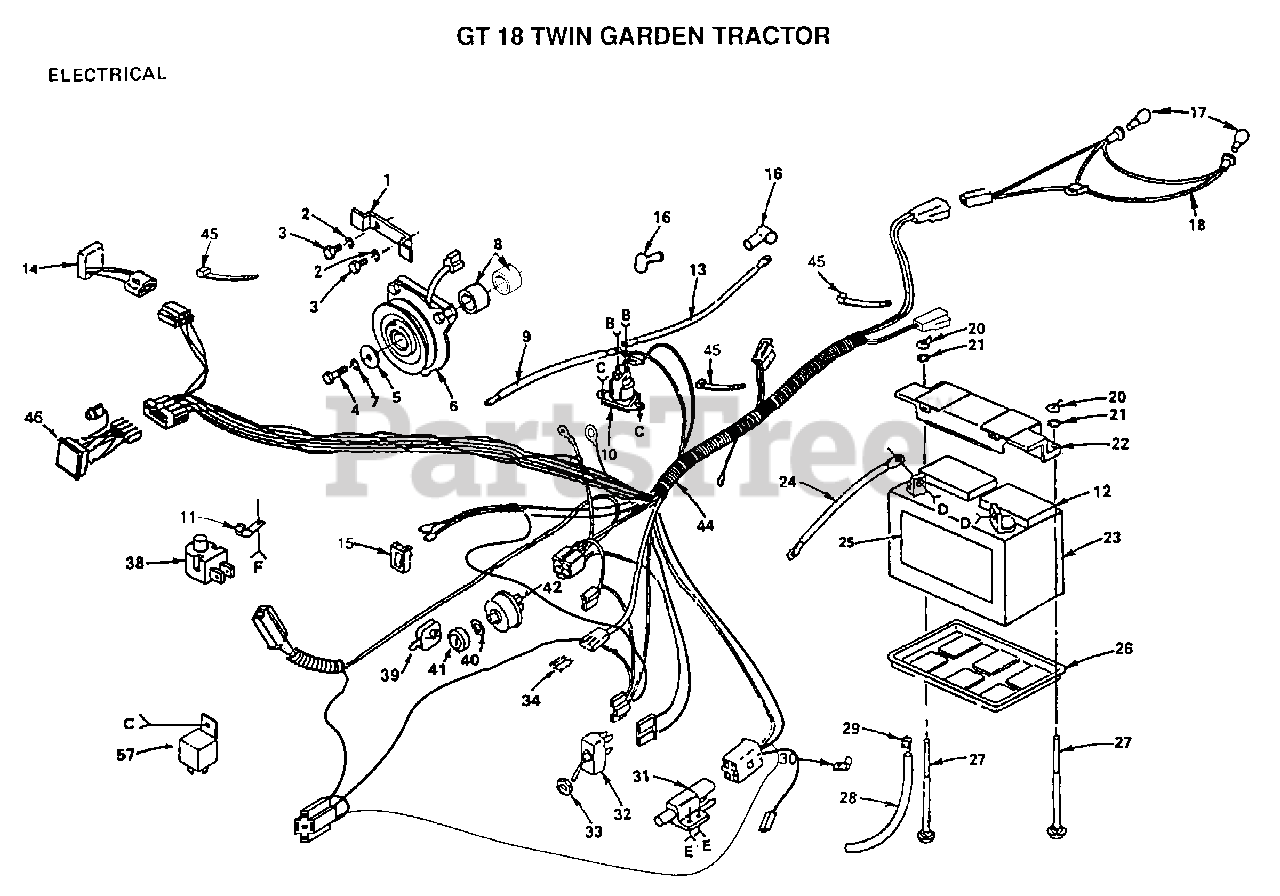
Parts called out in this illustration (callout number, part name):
2	LOCKWASHER
3	BOLT
5	WASHER T
6	CLUTCH.ELECTRIC.T
7	LOCKWASHER
8	SPACER-CLUTCH GT
9	CABLE-BATTERY T
12	"CAP,BATTERY "
15	SWITCH LT
18	HARNESS T
21	LOCKWASHER GT
24	CABLE T
25	DECAL
26	"TRAY T, BATTERY"
27	BOLT
29	HOSE CLAMP T
30	CLIP GTV
31	SWITCH INTERLOCKT
32	SWITCH T
33	HEX NUT T
34	FUSE-30 AMP
38	SWITCH SEAT
39	KEY
45	WIRE TIE
46	INDICATORLIGHTT
57	RELAY ASSY T
